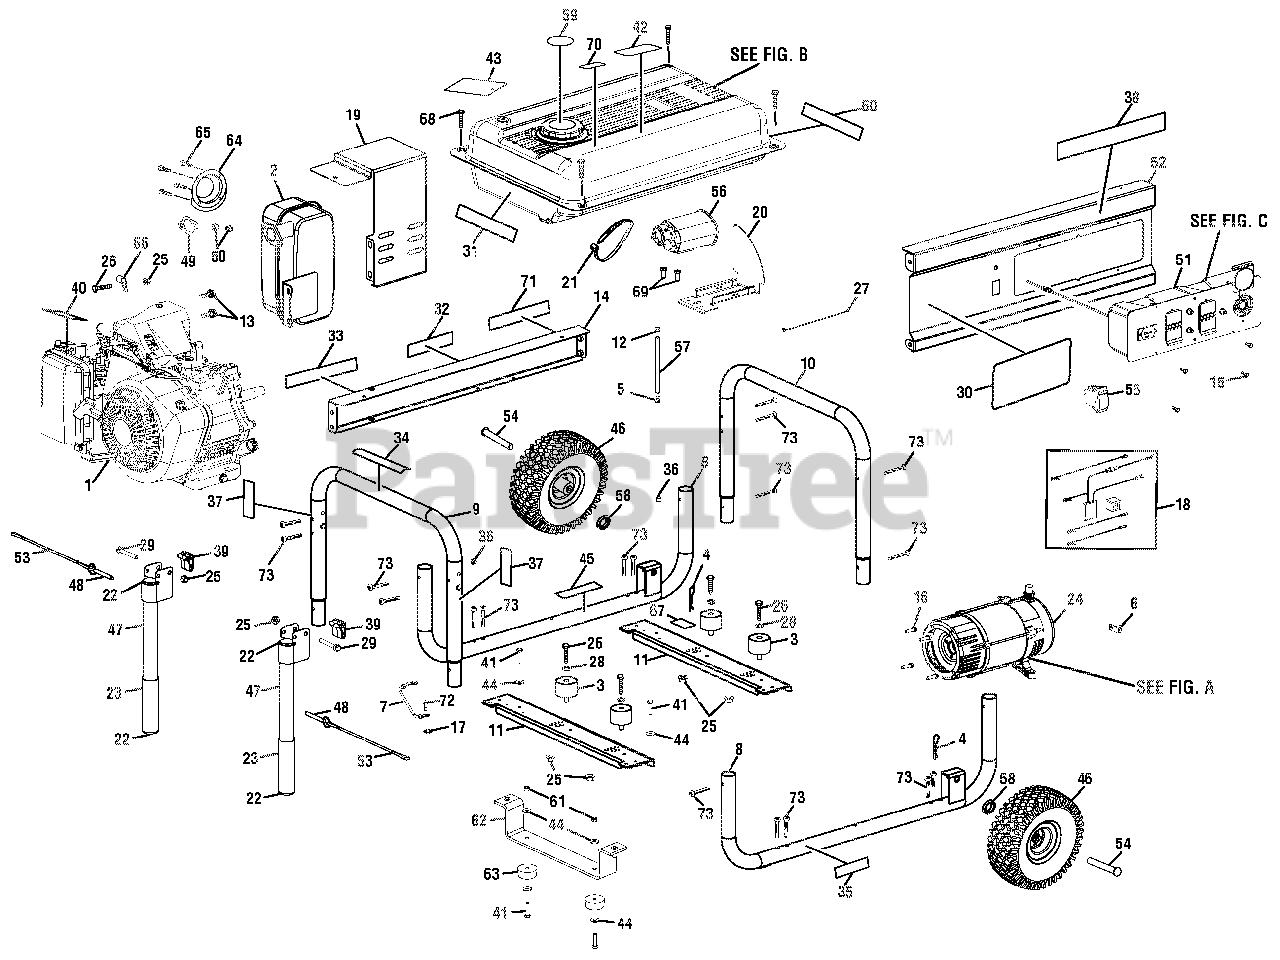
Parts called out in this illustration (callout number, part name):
1	Engine (Subaru) (Parts available at your local Subaru dealer)
3	Isolator
4	Hitch Pin
5	Clamp (3/8 in.)
6	Ground Lug
7	Ground Wire Assembly
8	Lower Frame Assembly
9	Tube Assembly (Left)
10	Tube Assembly (Right)
11	Cross Brace
12	Clamp (1/2 in.)
13	Bolt (5/16-24 x 5/8 in.)
14	Back Panel
15	Screw (6-20 x 3/8 in.)
16	Bolt (3/8-16 x1.25 in.)
17	Star Washer (M6)
18	Wire Harness
19	Heat Shield
20	Bracket (Carbon Canister)
21	Cable Tie
22	Plastic Cap
23	Handle Grip
24	Generator Head w/AVR
25	Lock Nut (M8)
26	Bolt (M8 x 35 mm, Hex Hd.)
27	Tie Wrap
28	Washer (M8)
29	Bolt (M8 x 55 mm, Hex Hd.)
30	Logo Label
31	Electric Start Label
32	Hot Surface Label
33	Danger Label
34	Fire Danger Label
35	Engine Lubricant Label
36	Lock Nut (M6)
37	Locking Pin Label
38	Subaru Label
39	Handle Bracket Spacer
40	Choke Label
41	Bolt (M6 x 1 in., Hex Hd.)
42	CPSC Label
43	Danger Hang Tag
44	Washer (ID6.4 x OD17 x 1.6t)
45	Combustion Warning Label
47	Handle Assembly (Inc. Key No. 22-23)
48	Release Pin (5/16 x 2 in.)
49	Exhaust Gasket
50	Lock Nut (M8)
51	Panel Assembly
52	Front Panel
55	Start Switch w/Lock
56	Carbon Canister Assembly
57	Purge Hose
58	Washer (1/2 in.)
59	Fuel Stabilizer Label
60	Ground Warning Label
61	Lock Nut (M6)
62	Foot Bracket
63	Rubber Foot
64	Spark Arrestor
65	Screw (8-32 x 3/8 in., Pan Hd.)
66	J-Clamp (1/2 in.)
67	Ground Label
68	Screw (1/4-14 x 1-1/4 in.)
69	Screw (#10-16 x 3/4 in.)
70	E85 Label
71	Fire Distance Label
72	Screw (M6 x 16 mm, Hex Hd.)
73	Screw (M6 x 50 mm, T30, Pan Hd.)
